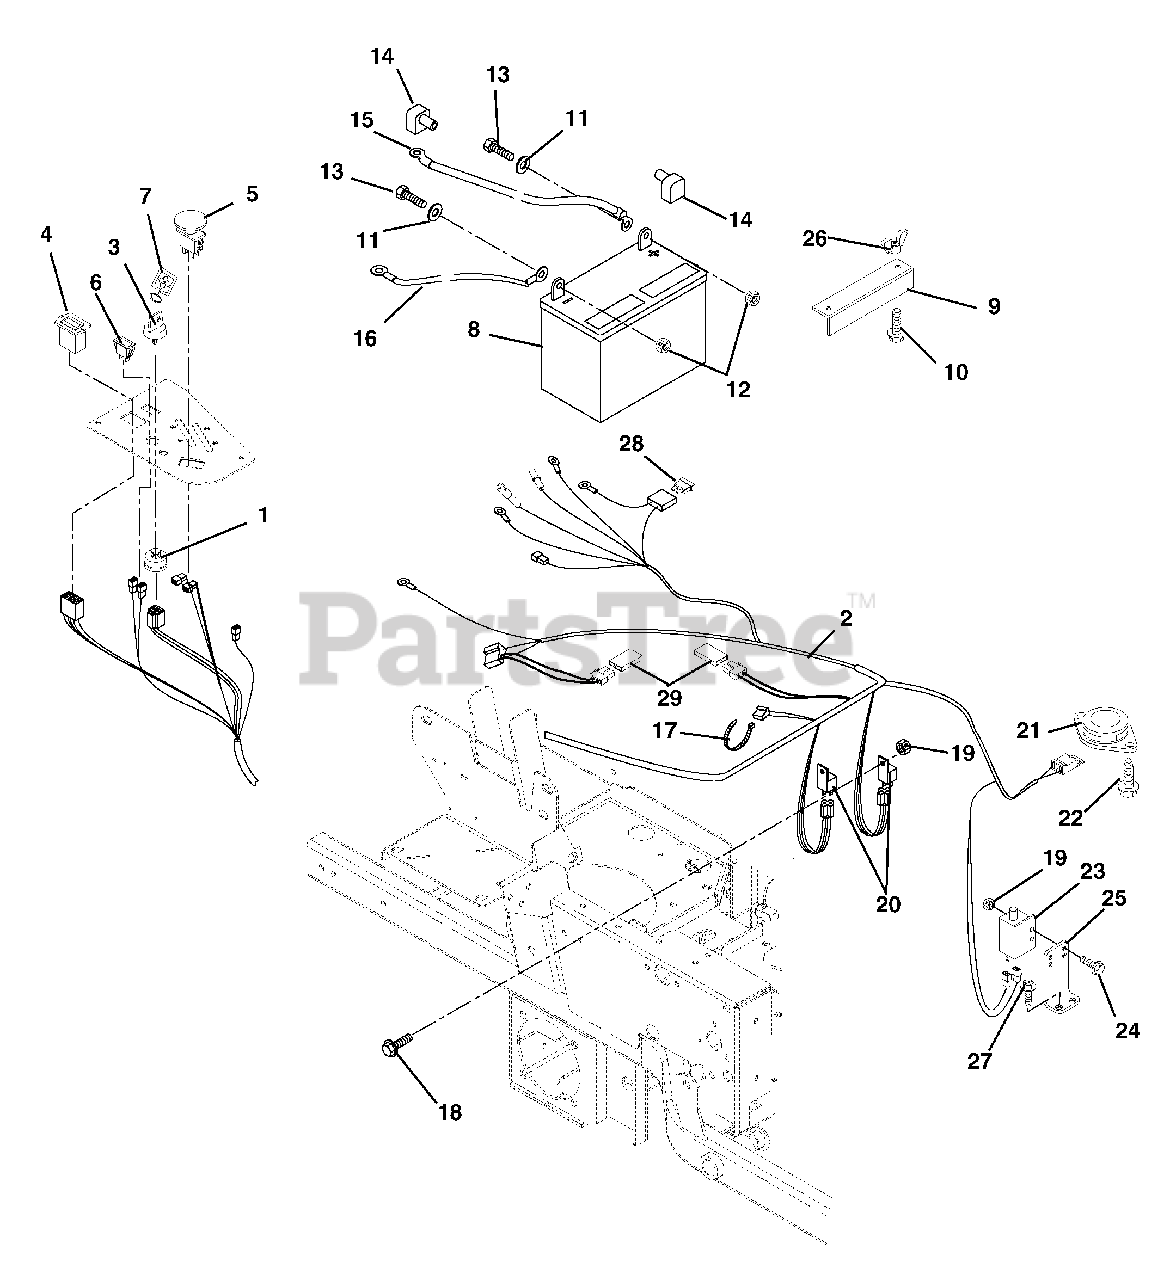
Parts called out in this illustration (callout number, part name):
1	Key Switch
2	Harness, Z 6-Pin Wiring
3	Key with Shield
4	Hour Meter
5	Switch, Clutch With Retainer Ring
6	Light, Indicator Kit
7	Key Chain
9	Hold Down
10	Bolt, Round Head Square Neck .25-20 x 7.50
11	Washer, Flat Steel .281 x .620 x .065
12	Nut, Locking Top Flange .25-20
13	Bolt, Hex .25-20 x .75 Grade 5
14	Insulator
15	Positive Cable 22"
16	Cable, Negative Battery
17	Cable Tie
18	Screw, Machine 10-24 x .50 Hex Washer Head
19	Nut, Locking Nylon 10-24 With Insert
20	Relay
21	Seat Switch
22	Screw, Tapping 12-24 x .50 Hex Washer Head
23	Switch, Single Pole
24	Screw, Machine 10-24 x .75 Hex Washer Head
25	Mount, Brake Switch
26	Nut, Locking Wing .25-20
27	Screw, Tapping .25-20 x .50 Hex Washer Head
28	Fuse, 30 Amp
29	Diode, Connector Shell
